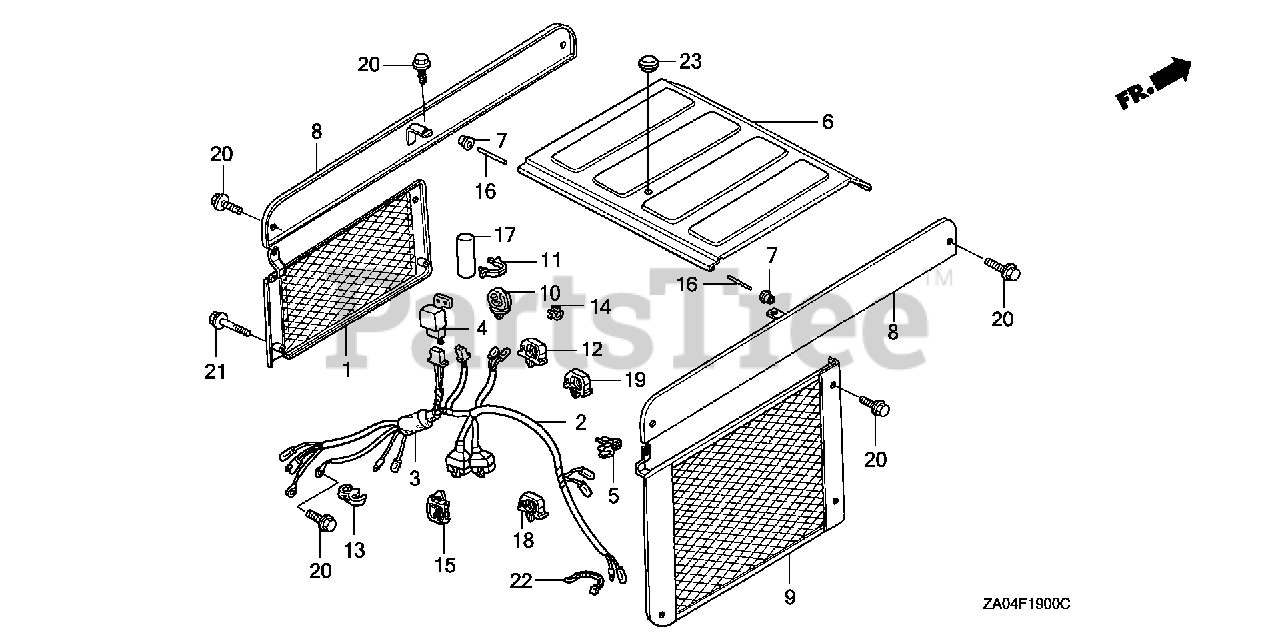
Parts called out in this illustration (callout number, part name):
1	COVER, MUFFLER *NH105* (MAT BLACK)
2	WIRE HARNESS ASSY.
5	CLIP, RECEIVER PIPE
5	CLIP, IGNITION WIRE
6	COVER, TOP *R280* (POWER RED)
7	BUSH, TOP COVER
8	COVER (UPPER) *R280* (POWER RED)
9	COVER, RADIATOR *NH105* (MAT BLACK)
10	CLIP, WIRE HARNESS
11	CLIP, WIRE HARNESS
12	CLIP, WIRE HARNESS (13MM) (GRAY)
13	CLIP, IGNITION WIRE
14	CLIP, ENGINE STOP SWITCH CORD
15	CLIP, WIRE HARNESS (25MM)
16	PIN, TOP COVER HINGE
17	TUBE, CORD (22MM)
18	CLIP, WIRE HARNESS
20	BOLT, FLANGE (6X12) Use up to Engine SN 1543277.
21	BOLT, FLANGE (6X28)
22	BAND (BLACK 3.5X140)
23	GROMMET, WASHER HOLE
